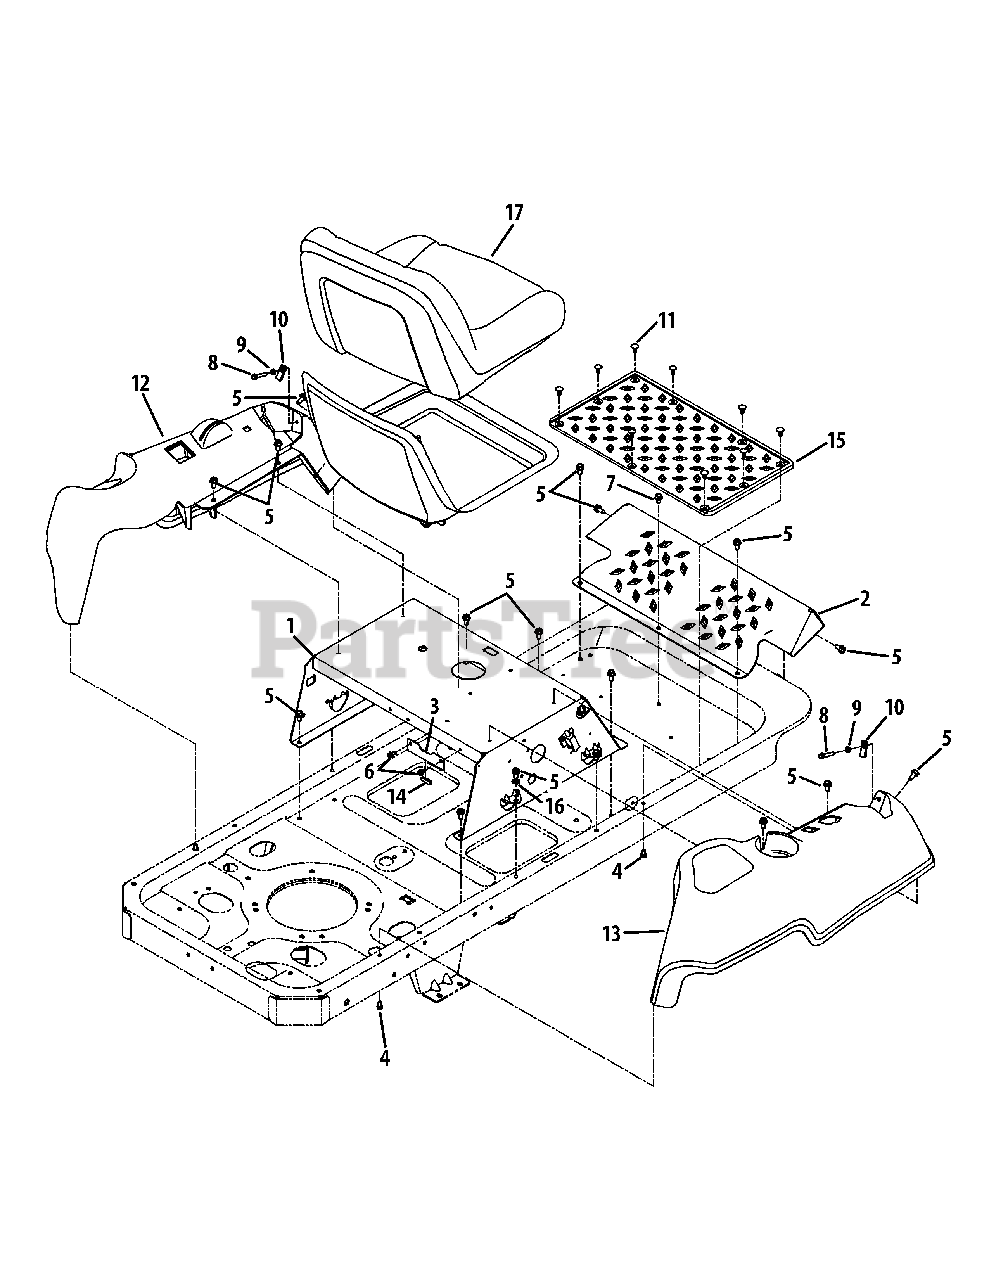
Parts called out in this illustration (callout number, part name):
1	Seat Frame Assembly (NLA) - Black Jack
1	Seat Frame Assembly - Black Jack
2	Foot Rest Bracket
3	Battery Hold-Down Bracket
4	Hex Washer Screw, 1/4-15 x .50
5	Hex Washer Screw, 5/16-18 x .750
6	Hex Washer Screw, 1/4-20 x .500
7	Hex Washer Screw, 5/16-18 x .625
8	Hex Washer Screw, 1/4-20 x 1.500
9	Jam Nut, 1/4-20
10	U-Type Nut, 1/4-20
11	Ratchet Clip
12	LH Console
13	RH Console
14	Trim Strip
15	Foot Pad
16	Lock Washer, 3/8
17	High-Back Seat
